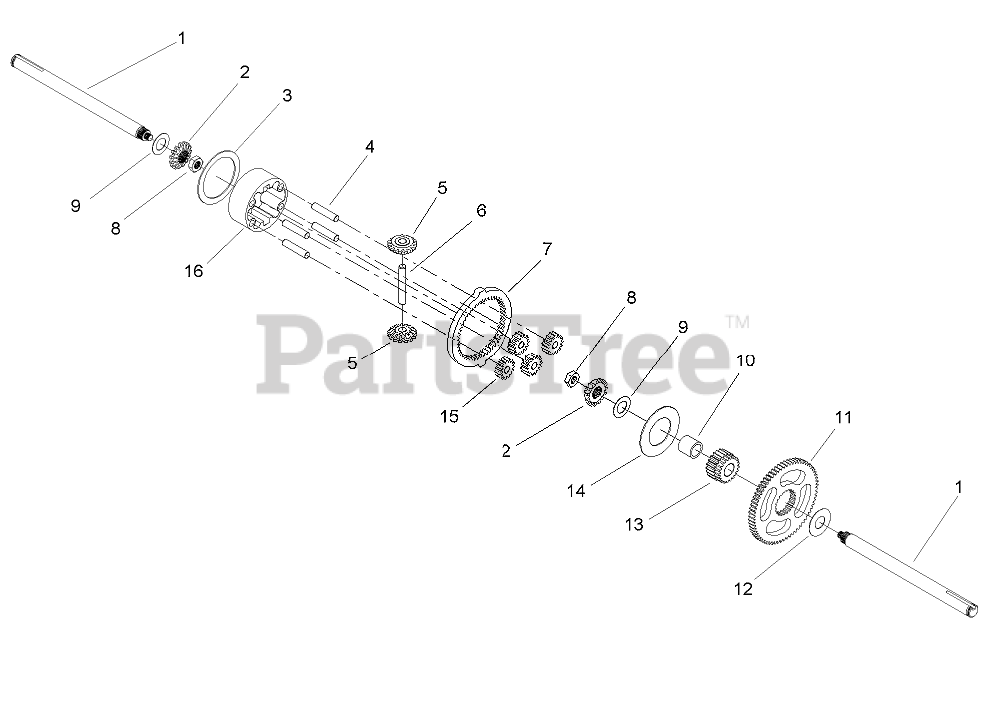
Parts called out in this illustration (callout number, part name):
1	SHAFT-AXLE
2	GEAR-MITER
3	PLATE-THRUST
4	PIN-CARRIER
5	GEAR-MITER
7	GEAR-RING, 51T
8	NUT-HJ
9	WASHER
10	BEARING-SLEEVE
11	GEAR-SPUR, 67T
12	WASHER
13	GEAR-SUN, 21T
14	PLATE-THRUST, PLANET
15	GEAR-PLANET, 15T
16	CARRIER-PLANETARY
